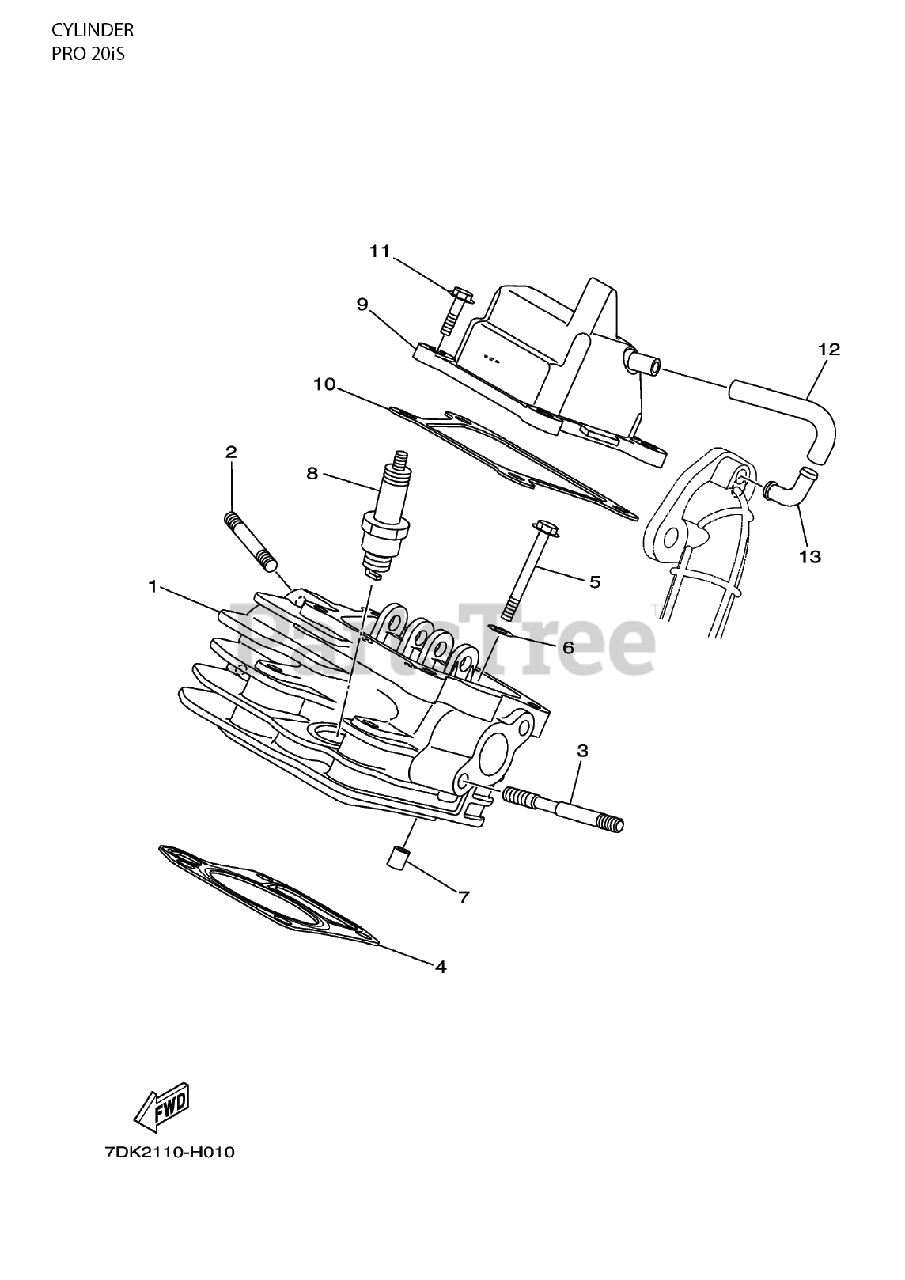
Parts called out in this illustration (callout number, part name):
1	HEAD, CYLINDER
2	STUD BOLDT
3	STUD BOLDT
4	GASKET, CYLINDER HEAD 1
5	SCREW - BOLT FLANGE
7	CRANKCASE 1
8	SPARK PLUG (NGK BPR6HS)
9	COVER, AIR CLEANER - COVER CYLINDER HEAD
10	GASKET, CYLINDER
11	SCREW - BOLT FLANGE
12	HOSE - PIPE, BREATHER 1
13	ELBOW, BREATHER - PIPE 1
